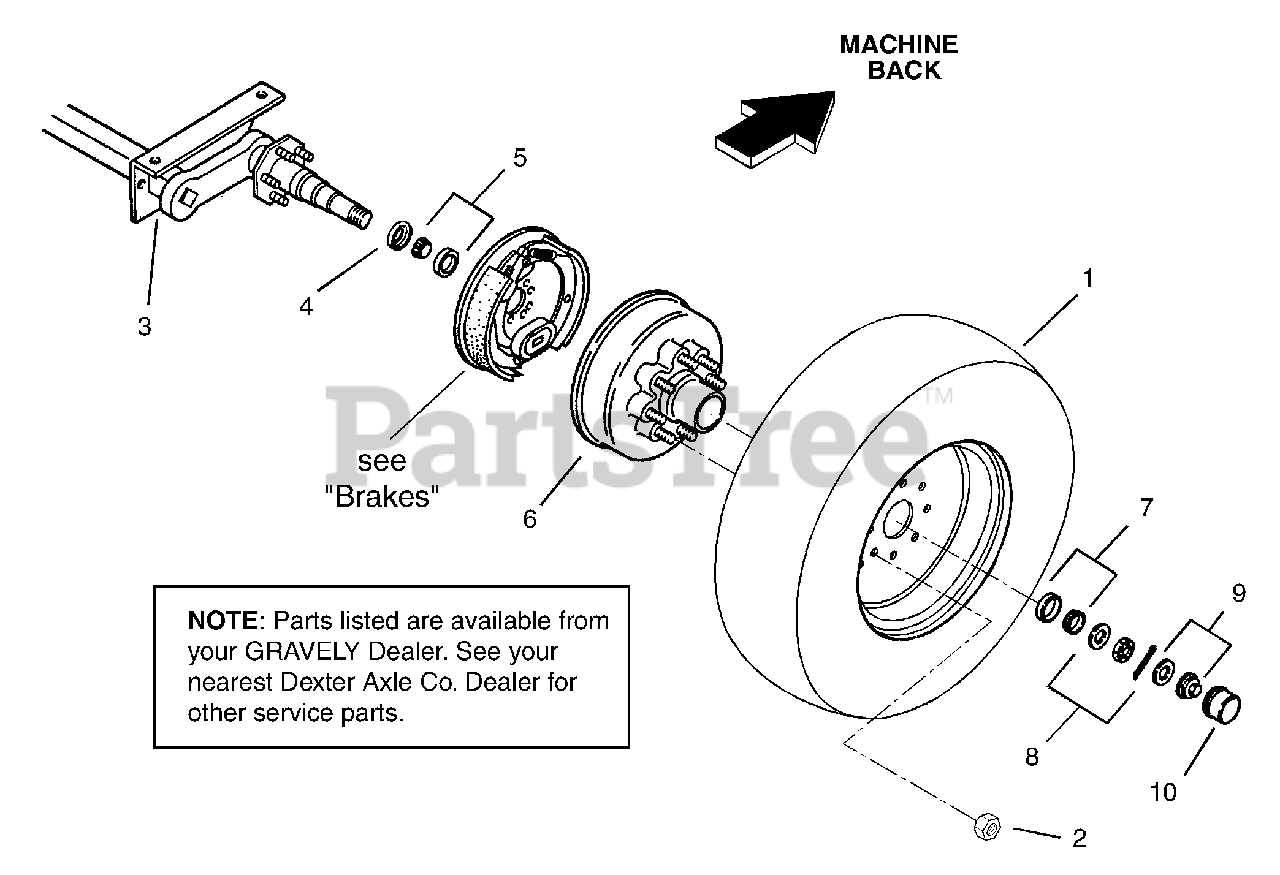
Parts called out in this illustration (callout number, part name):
1	Tire/Rim Assembly
2	Wheel Nut .50-20 13/16 Across Flats Automotive Type
3	Axle-6000 lb 8 Lug Hydraulic Surge
3	Axle-6000 lb 8 Lug Electric Brake
4	Grease Seal
5	Inner Bearing Cup & Cone
6	Hub & Drum
6	Hub & Drum-Electric
7	Outer Bearing Cup & Cone
8	Hardware Kit
9	Plug
10	Grease Cap
